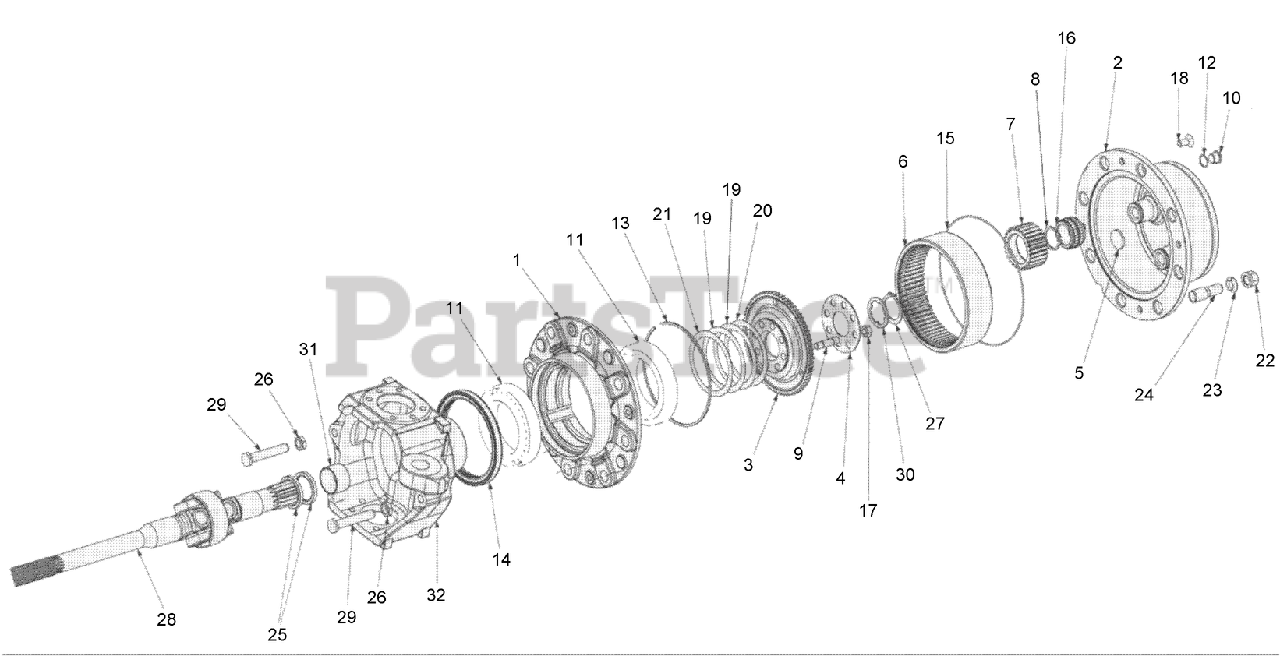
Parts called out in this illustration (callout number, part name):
1	HUB-WHEEL
2	HUB-Planetary
3	FLANGE-Crown
4	RING-Crown
5	SHIM-Crown Wheel
6	WHEEL-Crown
7	GEAR-Planetary
8	RING-SNAP
11	Bearing
12	WASHER-Copper
13	RING-Internal Retaining
15	O-RING
23	WASHER-Elastic
27	RING-SNAP
29	SCREW-Steering, End
30	SHIM-Crown
31	Bushing
32	JOINT-LH, Articulated
